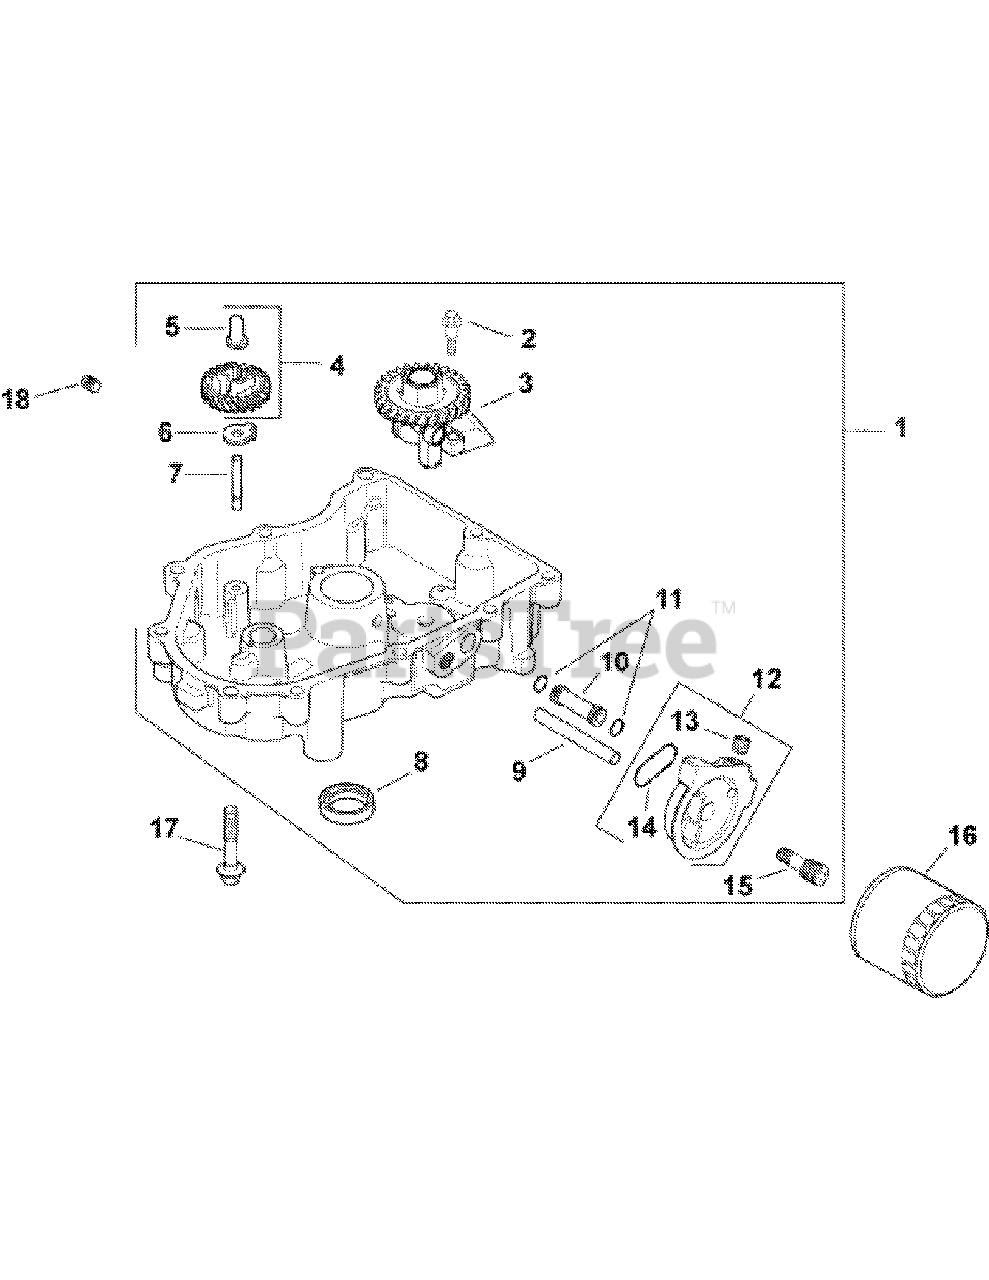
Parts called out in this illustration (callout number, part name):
1	PAN ASSEMBLY, OIL - USE 32 199 04-S
2	SCREW, SHD THD FRM M6x1.0x26.5
3	PUMP ASSEMBLY, OIL
4	KIT, GOVERNOR GEAR W/PIN
5	PIN, GOVERNOR REGULATING
7	SHAFT, GOVERNOR GEAR
9	TUBE, OIL FEED - FILTER TO PAN
10	TUBE, OIL FEED - PAN TO FILTER
11	O-RING, OIL PICK-UP
13	PLUG, CTSK PIPE 1/8"
14	O-RING, OIL FILTER ADAPTER
15	NIPPLE, OIL FILTER
17	SCREW, FLG M8X1.25X45
18	PLUG, SQ HD PIPE 3/8"
